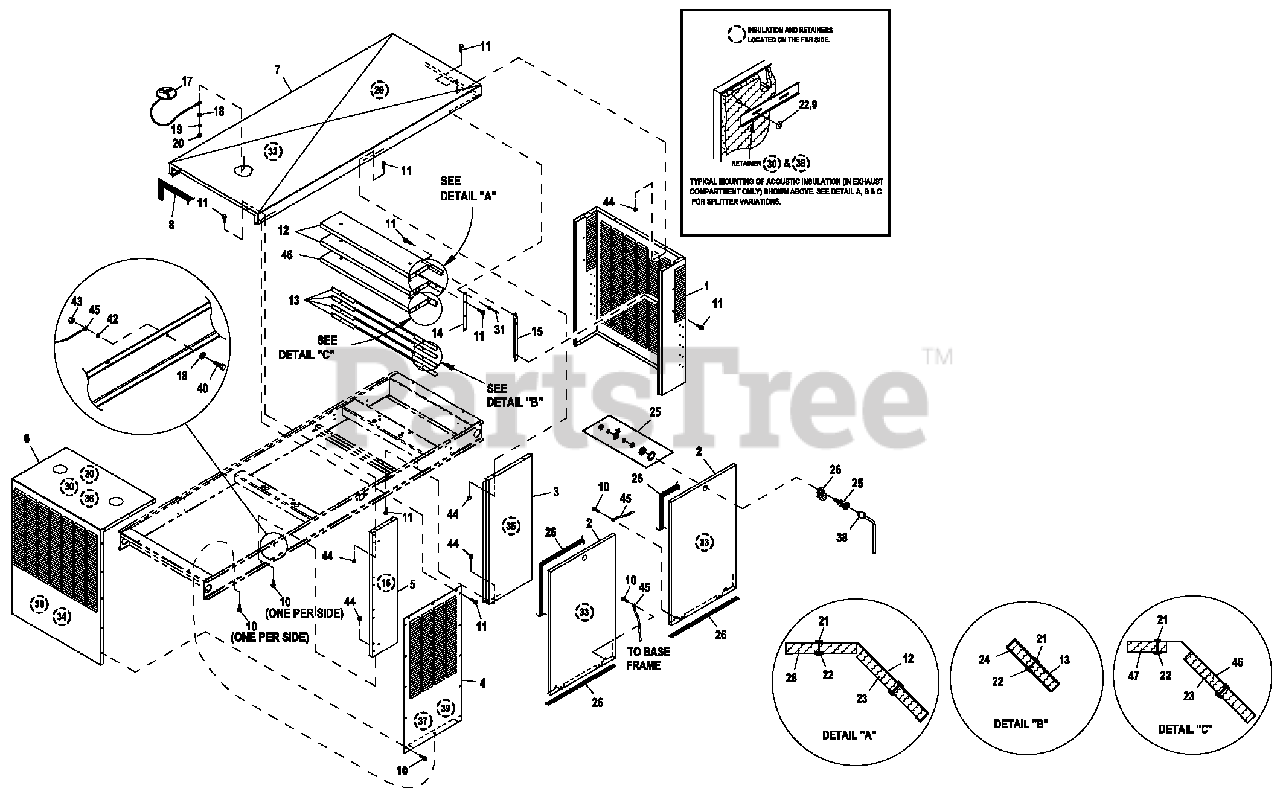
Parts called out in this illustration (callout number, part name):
1	REAR WRAP C5
2	DOOR C5
3	CENTER SUPPORT C5
4	DISCHARGE DUCT LH & RH SIDE C5
5	FRONT CORNERS C5
6	DUCT CENTER DISCHARGE RAW
7	ROOF C5ALUM
8	STRIP SEALANT 1/8X1 (44.5"LG)
9	WASHER SELF LOC KING DOME #8-32
10	SCREW TH-FRM M6 W/CAP SH KPRF W
11	SCREW THF M6-1 X 16 N WA Z/JS
12	SPLITTER
13	SPLITTER SHORT
14	STRINGER SPLITTER C3
15	SUPPORT SPLITTER C5 130 KW
16	INSUL CORNER POST
17	ASSY ACCESS COVER
18	WASHER FLAT 1/4-M6 ZINC
19	WASHER LOCK M6-1/4
20	NUT HEX 1/4-20 STEEL
21	INSULATION RETAINMENT HANGER
22	WASHER SELF LOC KING DOME #4-40
23	INSUL SPLITTER
24	INSUL SHORT LOUVER
25	VISE-ACTION LATCH SLOTTED CIR
26	GAS KET EXTRUDED TRIM (566" LG)
27	PULL TAB DOOR LOC K SS
28	INSUL SPLITTER SML
29	INSUL ROOF TOP REAR
30	RETAINER INSULATION (740)
31	RIVET POP.1875 X .450 SS
32	INSUL ROOF TOP FRT
33	INSUL DOOR
34	INSUL DISCHARGE DUCT
35	INSUL CENTER SUPPORT
36	INSUL DISCHARGE DUCT TOP
37	INSUL INNER DUCT SIDE
38	KEY VISE-ACTION LATCH SLOT CIR
39	RETAINER INSULATION (450)
40	SCREW HHC M6-1.0X20 G8.8
42	WASHER SHA KEPROOF INT 1/4
43	NUT HEX M6X1.0 G8 YELCHR
44	NUT HEX LOC K M6-1.0 SS NY INS
45	ASSY WIRE 14AWG GRN/YEL
46	SPLITTER C5
47	INSUL SPLITTER SHRTMPS
